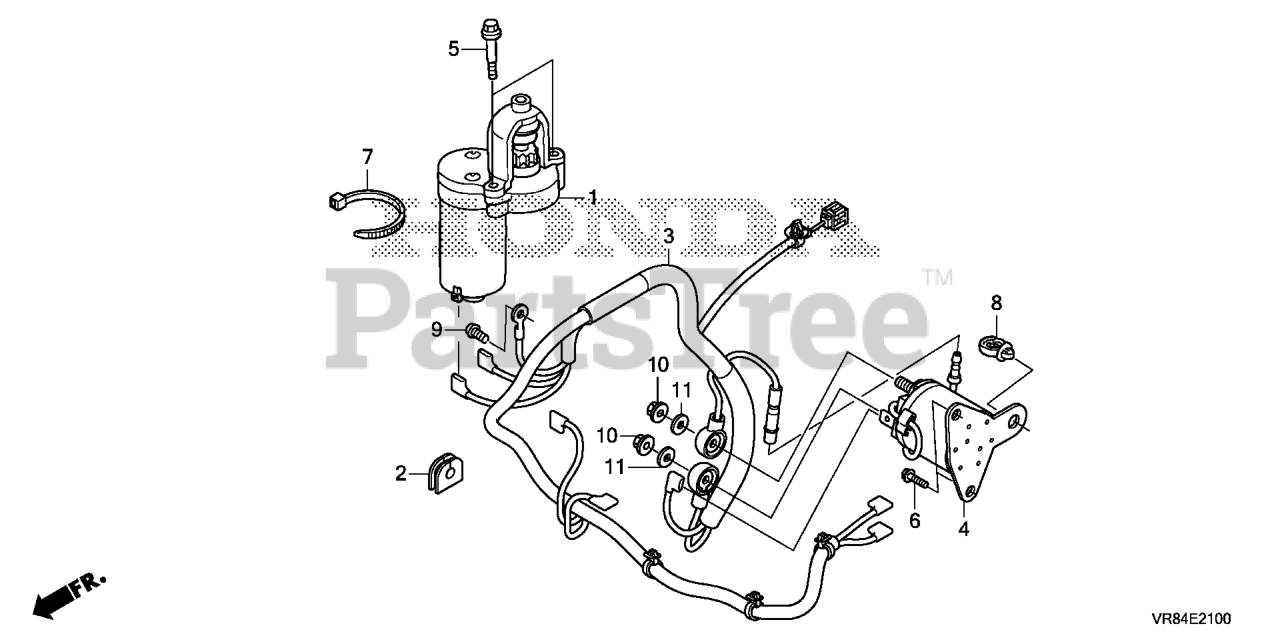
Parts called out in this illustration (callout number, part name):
1	STARTER MOTOR ASSY.
2	GROMMET, WIRE
3	WIRE HARNESS ASSY., ENGINE (SEL)(ZONE)
4	SWITCH ASSY., STARTER MAGNETIC
5	BOLT, SPECIAL (6MM)
6	BOLT, FLANGE (5X10) Use from Engine SN 2327377.
7	BAND, WIRE HARNESS
8	CLIP, WIRE HARNESS (25MM)
9	SCREW, PAN (5X8)
10	NUT, FLANGE (6MM)
11	WASHER, PLAIN (6MM)
